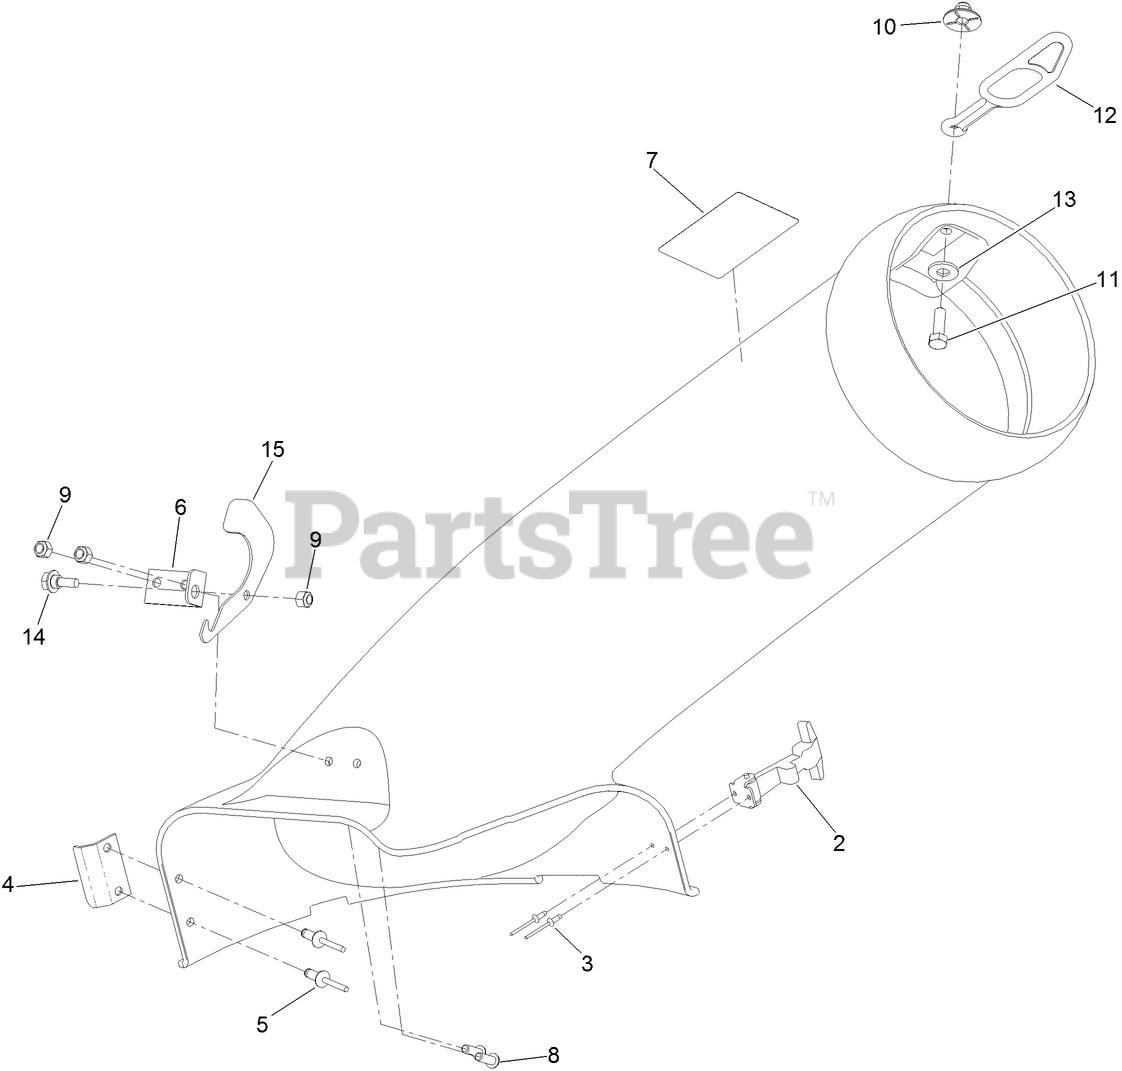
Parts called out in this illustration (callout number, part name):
2	HANDLE ASM
3	RIVET-POP
4	BRACKET-ELBOW
5	RIVET-BLIND
6	PLATE-PIVOT
7	DECAL-DANGER
8	SCREW-HSBH
9	NUT-LOCK, NI
10	NUT-IMPELLER
11	SCREW-HH
12	RETAINER-DUCT
13	WASHER-FLAT
14	SCREW-SHOULDER,HWH
